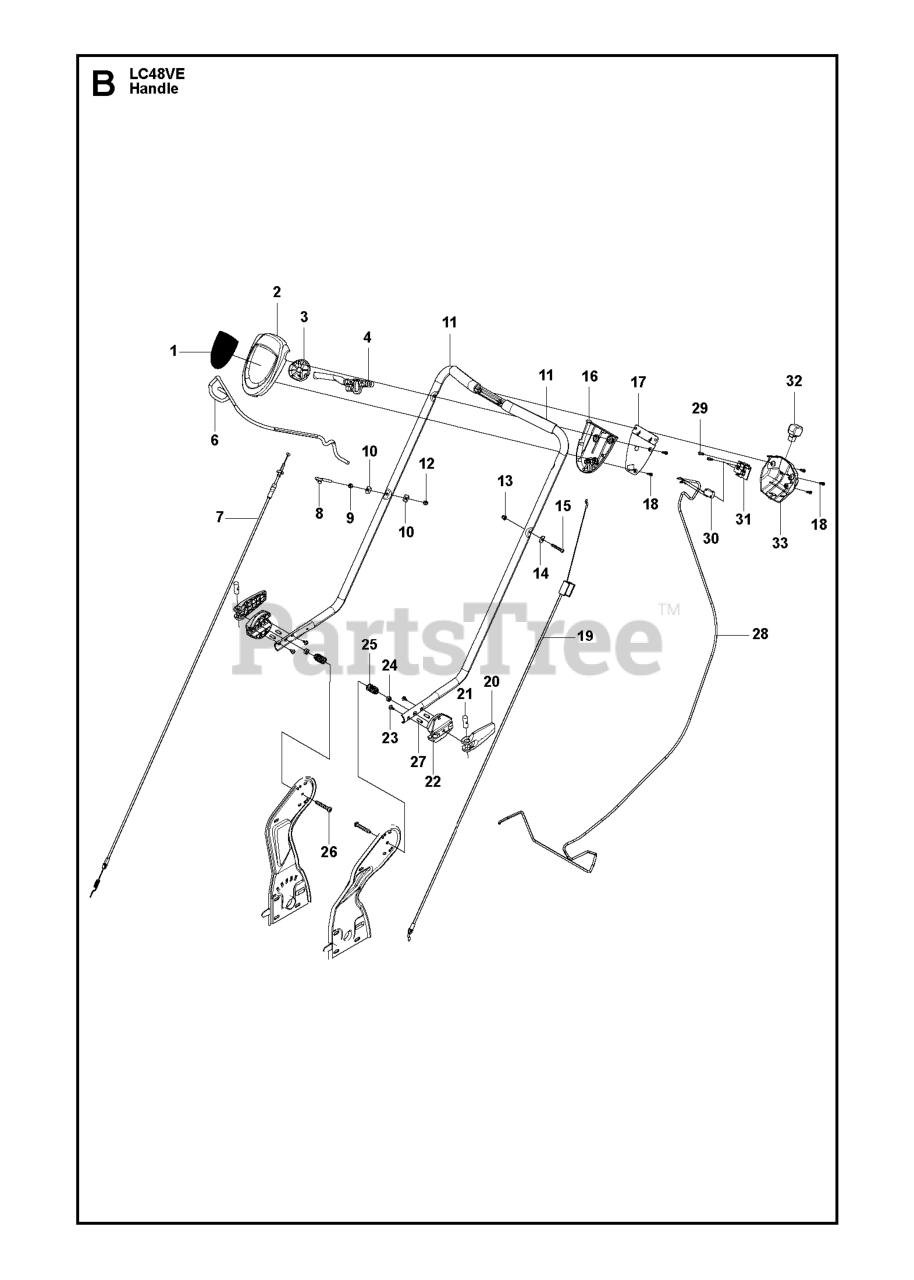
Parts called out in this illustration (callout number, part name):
2	COVER, DRIVE CONTROL BOTTOM
3	PULLEY.CAM.DRIVE.CONTROL.EZ
4	LEVER, DRIVE CONTROL
18	SCREW ITXPANT T50X16 ZN/FE (A
23	SCREW ITXPANTT M5X10 ZPB (A00
29	SCREW ITXPANT T50X16 ZN/FE (A
30	%BRAKER
